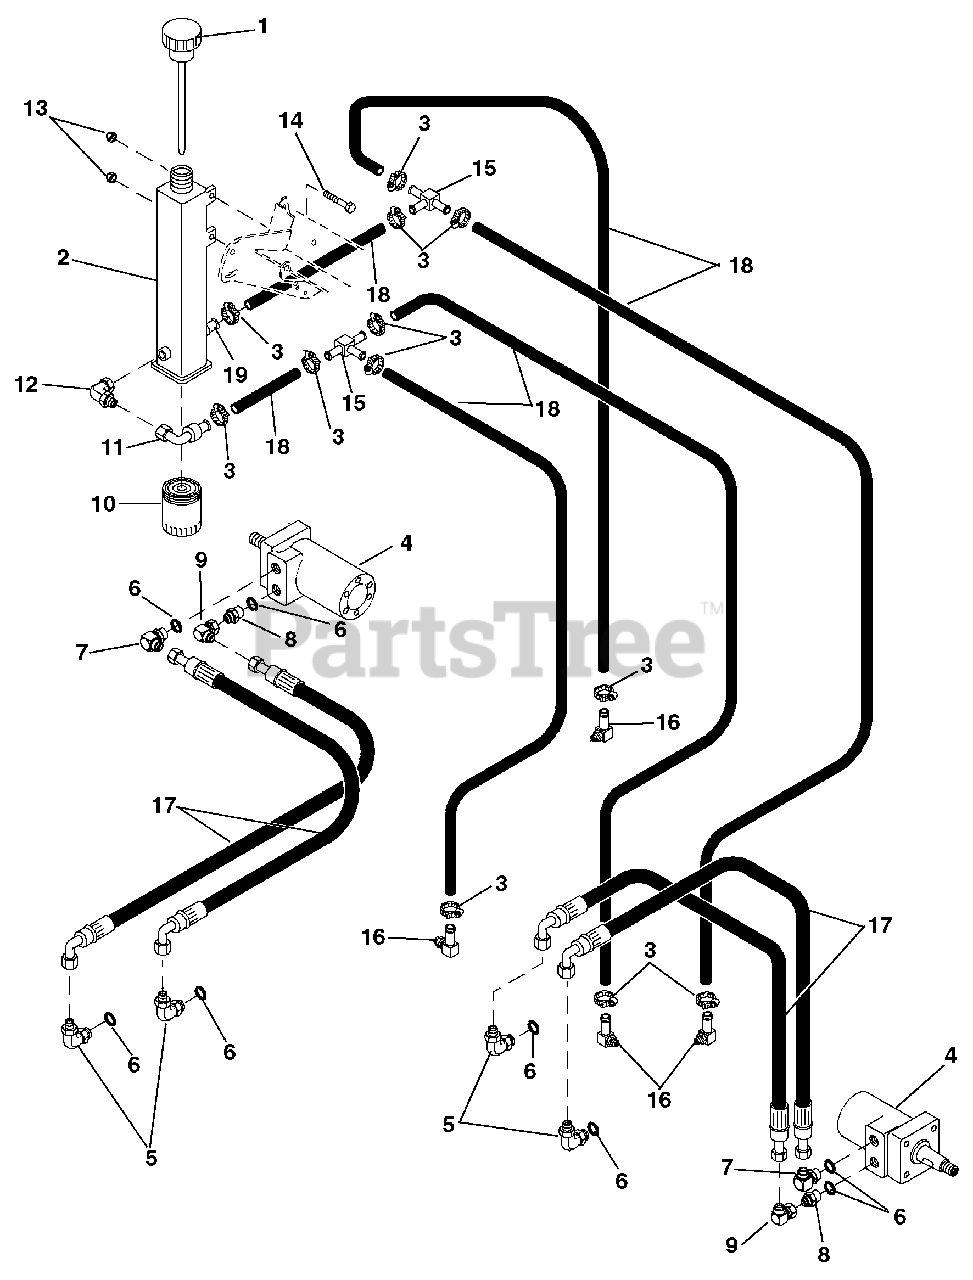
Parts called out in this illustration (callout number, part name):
1	Cap
2	Hydraulic Reservoir, Includes Decal
3	Hose Clamp
4	Wheel Motor
5	Fitting, Includes O-Ring
6	O-Ring, Included With Fitting
7	Adapter, 7/8 ORB x 3/4JIC x 90
8	Adapter, Hydraulic, 3/4-16MJIC x 7/8-14 MOR
9	Adapter, 3/4 FESW x 3/4 MJIC x 90
10	Element, Oil Filter
11	Elbow Fitting
12	Adapter 2503-6-6
13	Nut, Locking, Nylon 3/8-16
14	Bolt, Hex 3/8-16 x 3/4 Grade 5
15	Tee Fitting
16	Fitting, Adapter .562-18 Steel Thread
17	Hose, High Pressure
18	Hose, Return, 25 Ft Black - Cut to Length
19	Adapter, Straight Fitting
